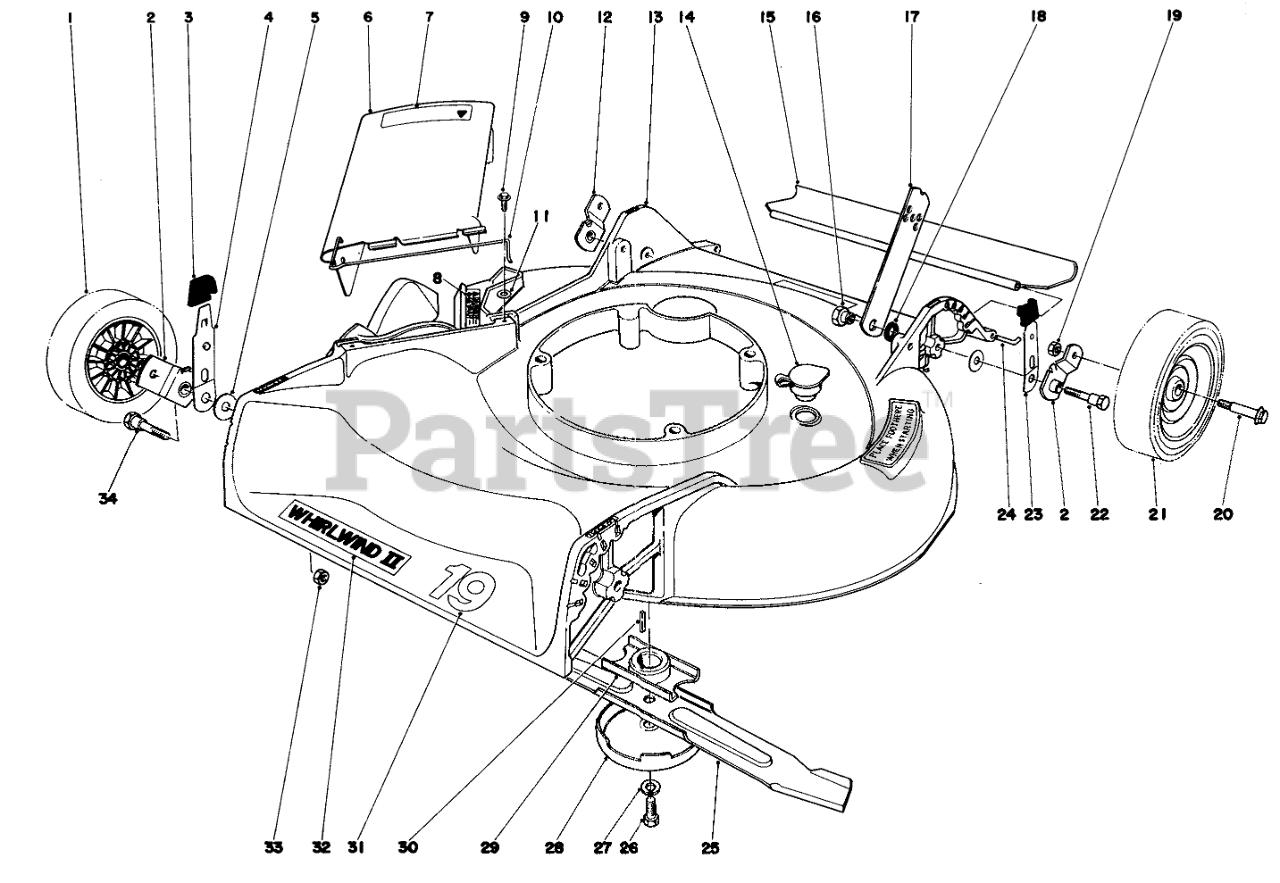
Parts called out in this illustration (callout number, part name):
1	Wheel & Tire Assembly
2	Pivot Arm
3	KNOB-ARM
4	SPRING ARM ASM
5	Washer
6	Deflector-Cover Assembly (Incl. Ref. #7 & 10)
7	Decal-Caution (French & Dutch)
8	Decal-Danger (French & Dutch)
9	SCREW
10	SPRING HINGE
11	WASHER-FLAT
12	Pivot Arm
13	Housing (Model 16009)
14	WASHOUT PLUG
15	SHIELD - TRAILING
16	HANDLE PIVOT NUT
17	Handle Latch
18	HANDLE LATCH SPACER
19	Nut
21	Wheel & Tire Assembly
22	PIVOT SCREW
23	SPRING ARM ASM
24	SHIELD ROD
25	Blade
26	SPECIAL SCREW
27	WASHER-LOCK
28	AntiScalp Cup
29	Blade Retailer
30	KEY-SQUARE
31	Decal-19"
32	Decal Whirlwind
33	Nut
34	PIVOT SCREW
